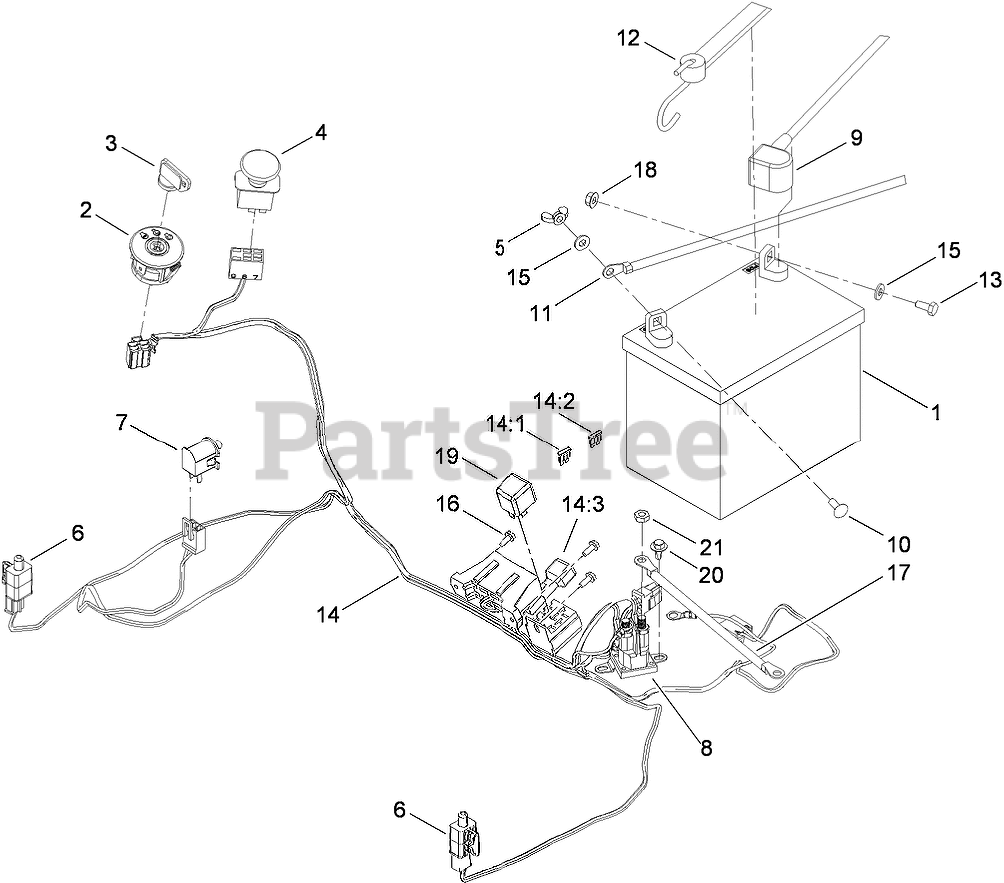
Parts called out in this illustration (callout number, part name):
1	BATTERY
2	SWITCH-IGNITION
3	KEY-IGNITION
4	SWITCH-PTO
5	NUT-WING
6	SWITCH
7	SWITCH-BAIL
8	SOLENOID
9	CABLE-BATTERY, RED
10	BOLT-CARR
11	CABLE-BATTERY, BLACK
12	HOLDDOWN-BATTERY
13	SCREW-HH
14	HARNESS-WIRING
14:1	FUSE-BLADE, 30 AMP
14:2	FUSE-BLADE, 25 AMP
15	WASHER-FLAT
16	SCREW-TAPTITE
17	CABLE-BATTERY, RED
18	NUT-HF
19	RELAY
20	SCREW-HHFTF
21	NUT-JAM
